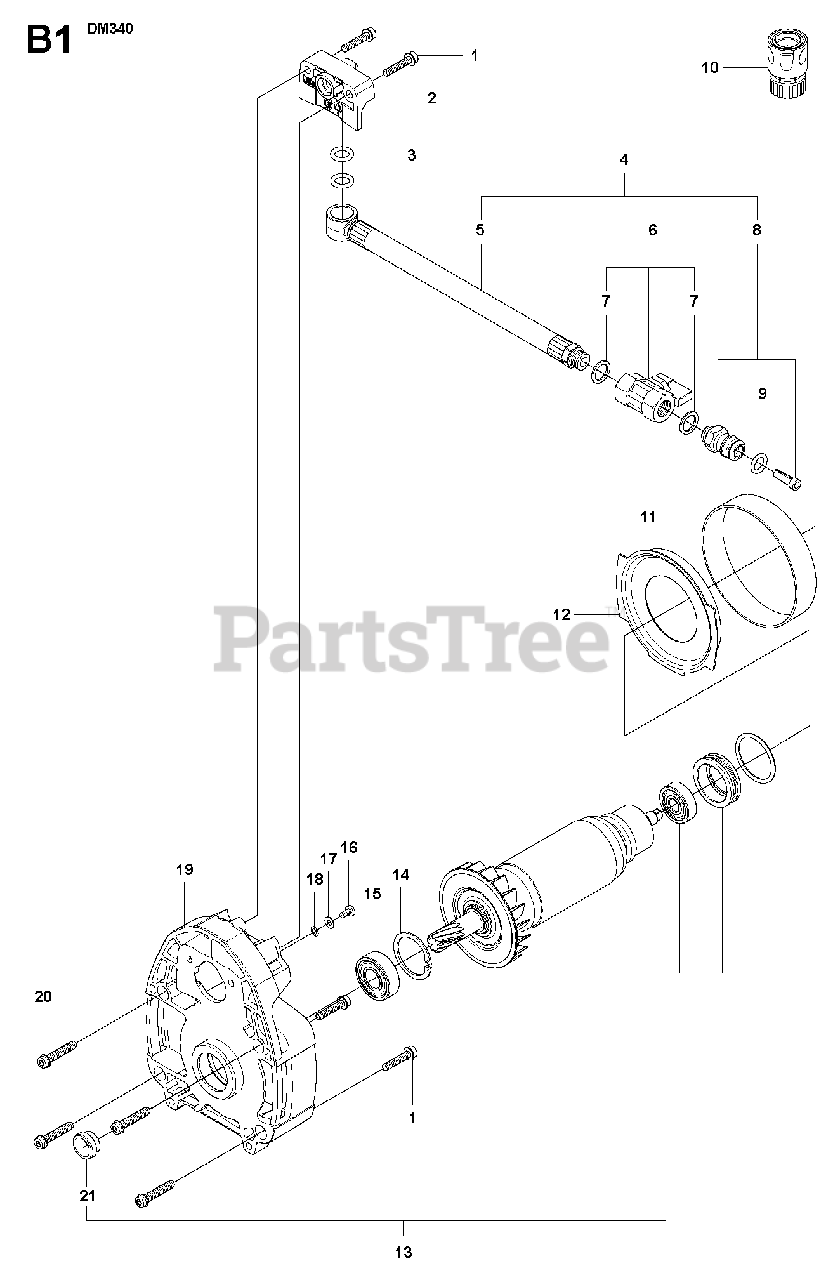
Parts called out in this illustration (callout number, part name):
1	SCREW IHSCFM
4	HOSE ASSYIncl 5, 6, 8
6	VALVE KITIncl 7
8	NIPPLEIncl 9
10	COUPLERUS, CANADA
15	BALL BEARING
16	SCREW CRPANM
